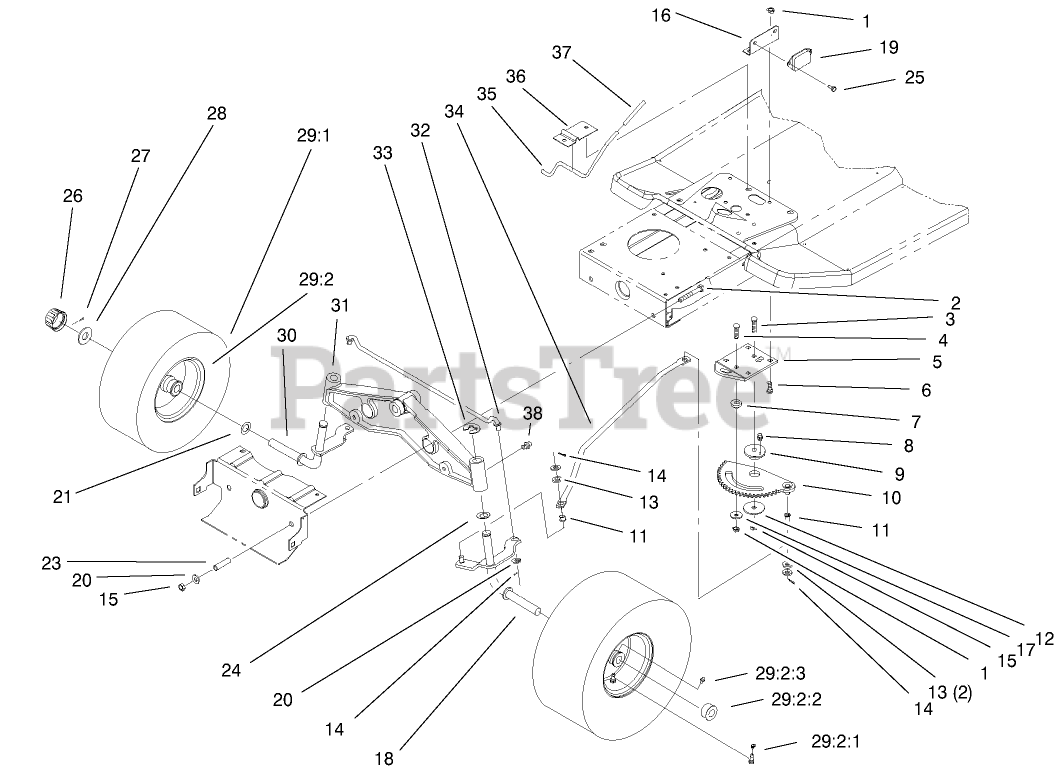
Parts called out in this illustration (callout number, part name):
1	NUT-LOCK, NI
2	SCREW-HH
3	SCREW-CARR
4	SCREW-CARR
5	BRACKET-RACK, STEERING
6	BOLT-CARR
7	SPACER-RACK, STEERING
8	FITTING-GREASE
9	BUSHING-ECCENTRIC
10	RACK-STEERING
11	BUSHING-FLANGED, NYLON
12	WASHER-BEARING
13	WASHER-FLAT
14	PIN-COTTER
15	NUT-LOCK, NI
16	BRACKET-MODULE
17	WASHER-PIVOT
18	LH SPINDLE ASM
19	MODULE
20	WASHER-FLAT
21	WASHER-THRUST
23	SPACER
24	WASHER-THRUST
25	SCREW-HWH
26	CAP-HUB
27	PIN-COTTER
28	WASHER-PLAIN
29:2	RIM ASM
29:2:3	FITTING-GREASE
30	RH SPINDLE ASM
31	AXLE-FRONT
32	TIE ROD-STEERING
33	E-RING
34	LINK-DRAG
35	ROD-BRAKE, PARKING
36	BRACKET-PARKING BRAKE
37	GRIP-BRAKE, PARKING
38	FITTING-GREASE
